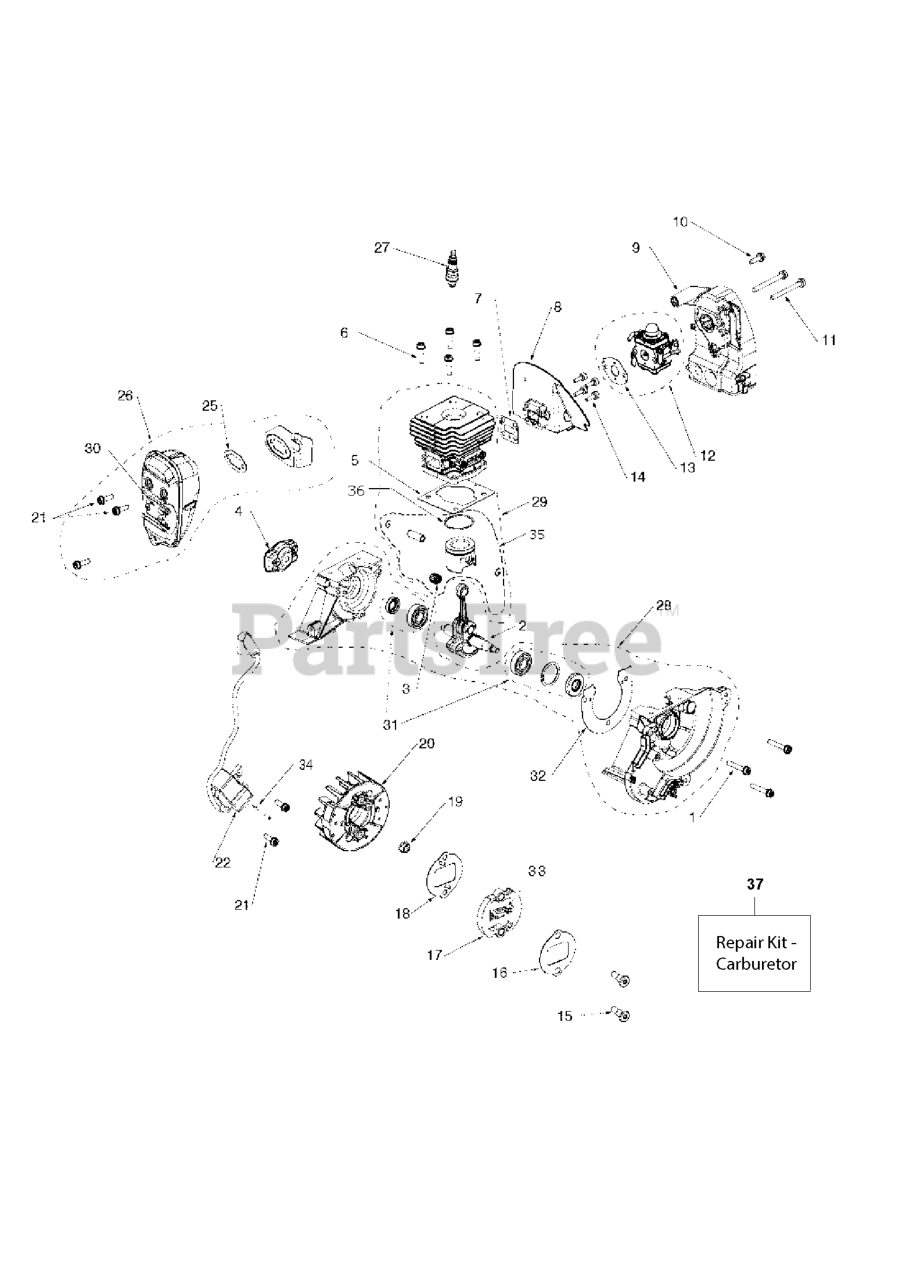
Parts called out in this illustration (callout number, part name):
2	CRANKSHAFT ASSY
4	STARTER PAWL BRIDGE
5	GASKET CYLINDER BASE
7	GASKET INSULATION WALL
8	ASSY INSULATION WALL
9	ASSY FILTER HOLDER
12	KIT CARBURETOR
13	GASKET CARB ADAPTER
14	SCREW ITXSCM
15	SCREW CLUTCH
16	WASHER CLUTCH UPPER
17	ASSY CLUTCH
18	WASHER CLUTCH LOWER
19	FLANGE NUT
22	Ignition Module
26	MUFFLER KIT
27	KIT SPARK PLUG
28	KIT CRANKCASE ASSY
29	KIT PISTON/CYLINDER
30	KIT SPARK ARRESTOR
31	SEAL KIT AND BEARING
32	GASKET CRANKCASE
33	SPRING CLUTCH
34	CABLE SHORT CIRCUIT ENGINE
35	KIT PISTON 129
36	PISTON RING 36MM
37	KIT CARB GASKET
